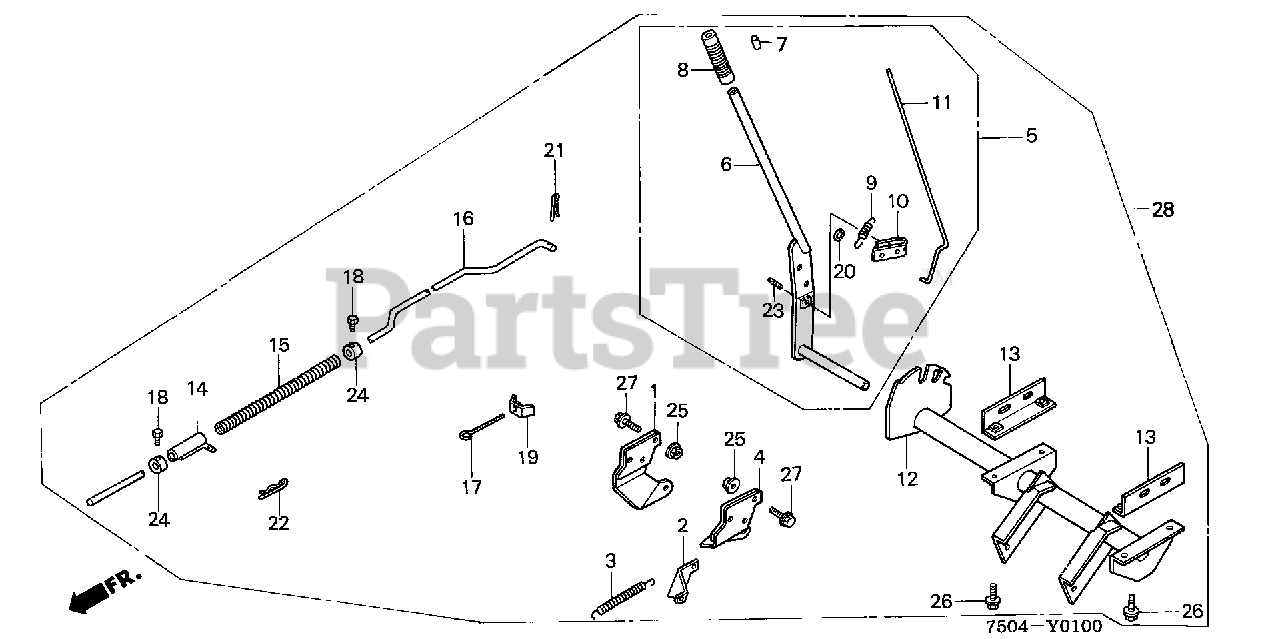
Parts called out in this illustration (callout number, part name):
1	STAY, R. FR. BRACKET
2	STAY, COUNTER SPRING
3	SPRING, COUNTER
4	STAY, L. FR. BRACKET
5	LEVER ASSY., LIFT
6	LEVER, LIFT
10	LATCH, LEVER
11	ROD, LATCH
12	BASE, LIFT LEVER
13	STAY, HANGER
14	GUIDE ASSY., ROD
17	BOLT, TENSIONER
18	SCREW, SETTING (5/16-18X1/2)
19	NUT, ADJUSTING
20	NUT, PUSH ON
21	CLIP, SPRING
22	CLIP, SPRING
23	PIN, SPRING (3/8X1)
24	COLLAR, SETTING
25	NUT, FLANGE (10MM)
26	BOLT, FLANGE (8X16)
27	BOLT, FLANGE (10X32)
28	LEVER KIT, LIFT
